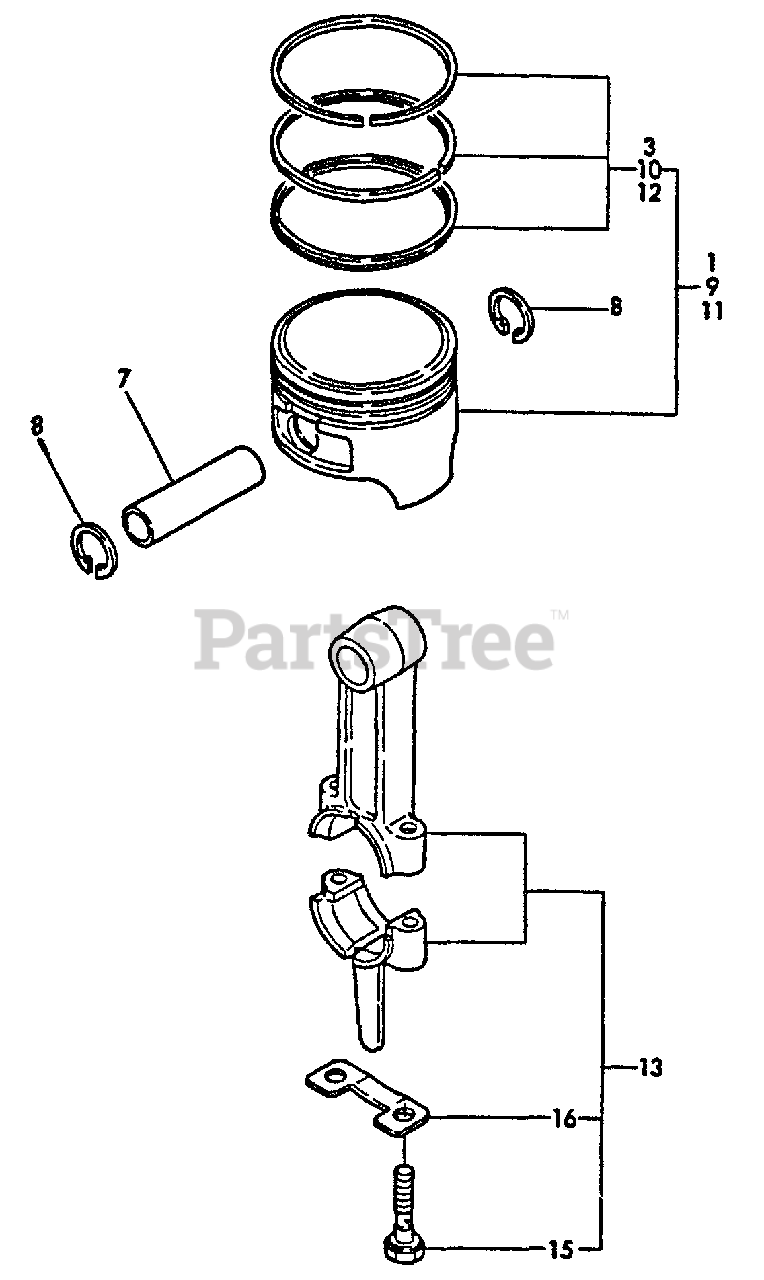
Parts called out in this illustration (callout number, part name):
1	PISTON ASSY
3	PISTON RING ASSY
7	PIN, PISTON
8	RING, RETAINING - 16
9	PISTON ASSY O.S.=0.25
10	RING ASSY O.S.=0.25
11	PISTON ASSY O.S.=0.5
12	RING ASSY O.S.=0.5
13	CONNECTING ROD ASSY
15	BOLT, ROD
16	WASHER
